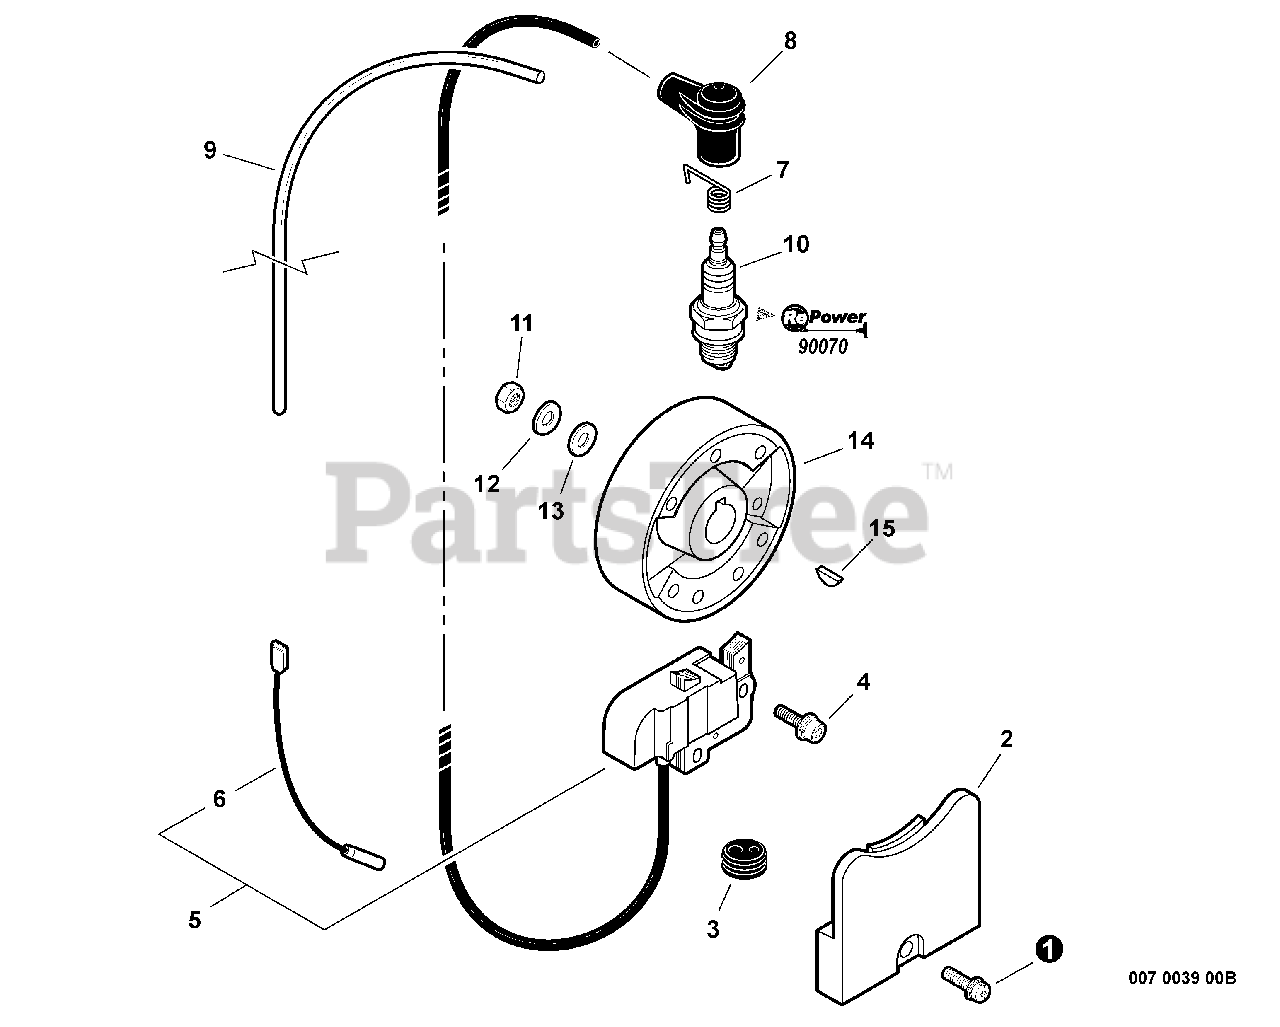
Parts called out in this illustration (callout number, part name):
1	SCREW - 5X18
2	COVER, DUST
4	SCREW - 5X18
5	COIL, IGNITION
6	LEAD - IGNITION
7	TERMINAL, SPARK PLUG CAP
8	CAP, SPARK PLUG
9	TUBE - VINYL
10	SPARK PLUG -- BPM-8Y
11	NUT - 10
12	LOCKWASHER - 10
13	WASHER - 10
14	FLYWHEEL
15	KEY - 3X14
16	RePower TUNE-UP KIT
